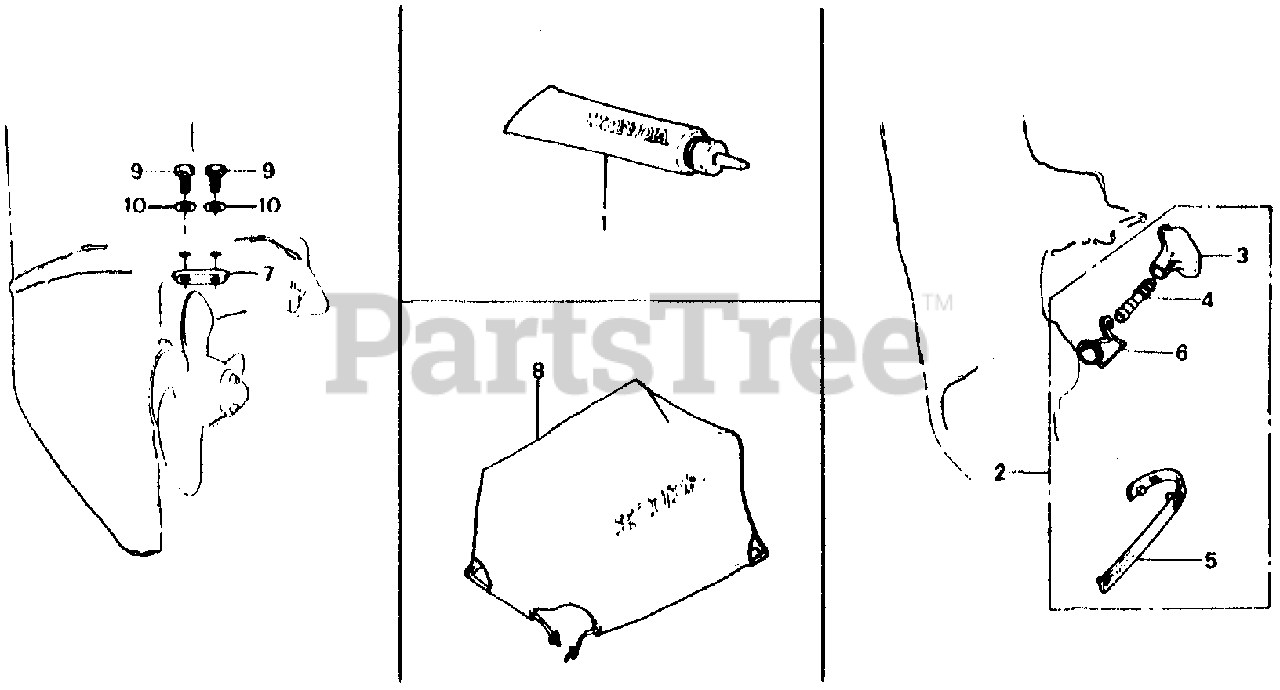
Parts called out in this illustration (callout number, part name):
1	TUBE, GEAR OIL
2	WATER MOUTH KIT
2	JOINT SET W/MOUTH
2	MOUTH SET, WATER
3	MOUTH, WATER
4	JOINT, HOSE (NOT AVAILABLE)
5	PLUG, WATER (NOT AVAILABLE)
6	CLIP, WATER MOUTH
8	COVER, BODY
